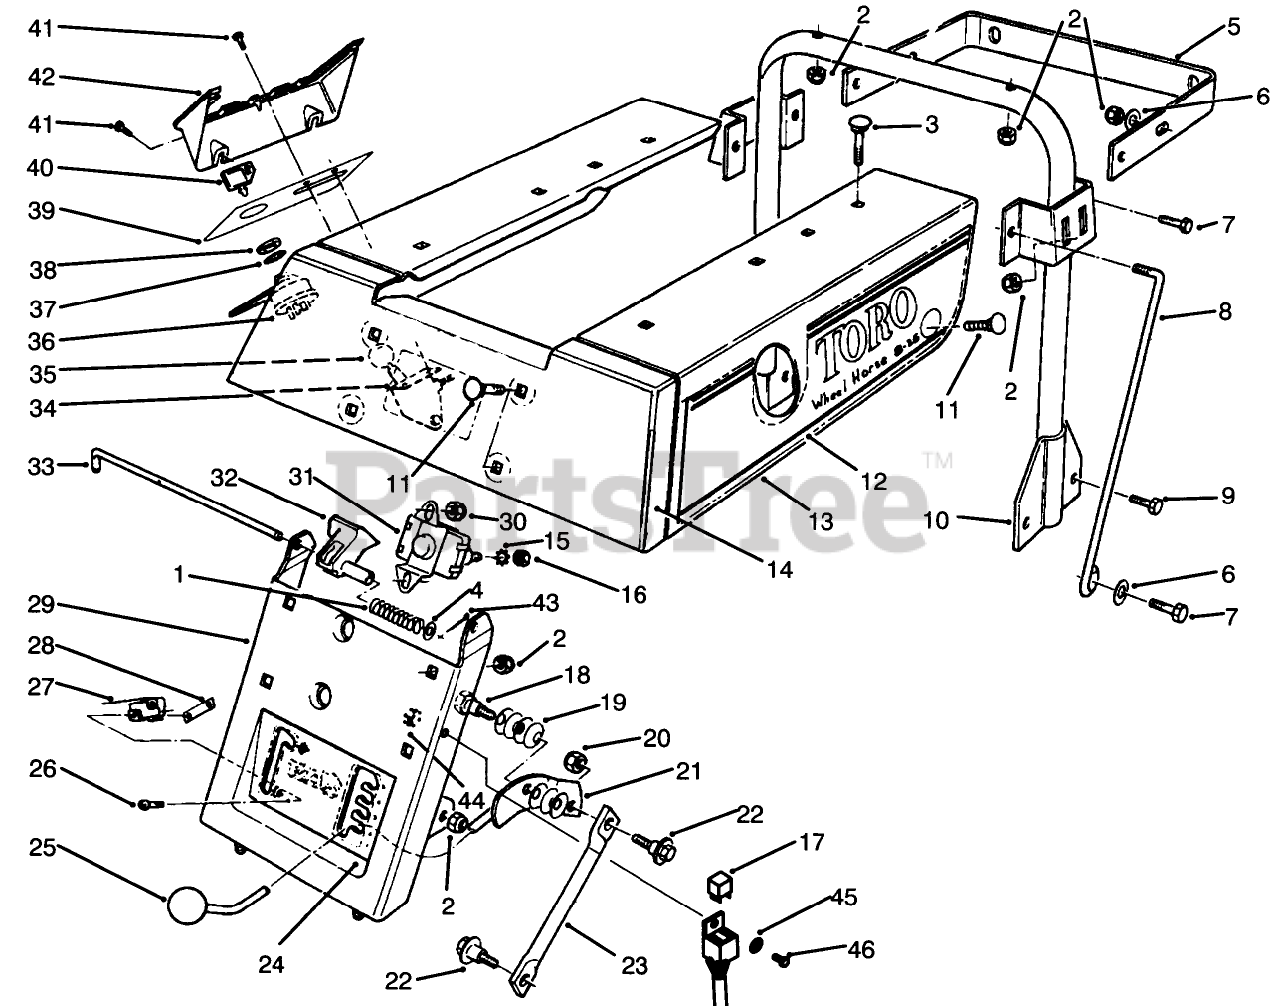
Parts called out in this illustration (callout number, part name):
1	SPRING-COMPRESSION
2	NUT-LOCK, NI
3	SCREW-CARR
4	WASHER-FLAT
5	STANDBAR
6	WASHER-PLAIN
7	SCREW-HH
8	SEAT SUPT ASM
10	Support W.A.-Seat
12	DECAL - LH SIDE PLATE
13	SEAT BODY WA
14	DECAL - W.H. INSIGNA
15	WASHER-LOCK/EXT
16	NUT-JAM
18	BOLT-SHOULDER
19	WASHER-BELLEVILLE
20	NUT-LOCK, NI
21	HOC HDLE WA
22	BOLT-SHOULDER
23	LINK-HOC
24	DECAL - HOC/DECK ENGAGE
25	KNOB-CONTROL
26	SCREW-SPH
27	SWITCH-MICRO
28	NUT-SPEED
29	SEAT SUPPORT ASM
30	NUT-LOCK, NI
32	PROP-SEAT
33	ROD-SEAT BASE
34	CONTROL-THROTTLE
36	SWITCH-STARTER
37	WASHER-LOCK
38	NUT-HH
40	KEY-IGNITION
41	SCREW-THD FORM, HWH
43	SCREW-HSH
44	NUT-LOCK, NI
45	WASHER-FLAT
